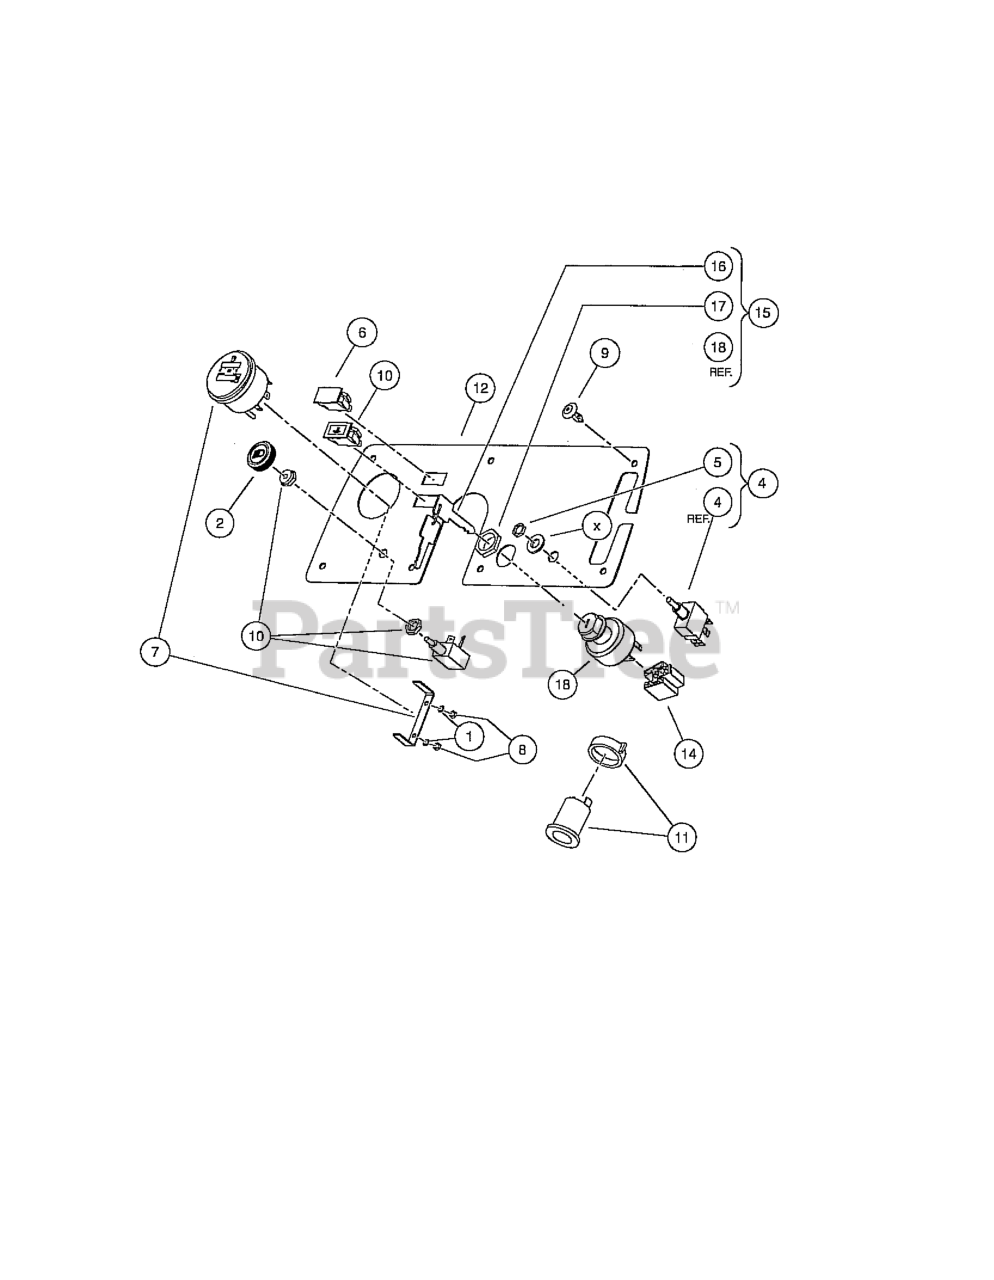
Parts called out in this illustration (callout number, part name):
1	Lockwasher, M4
2	LIGHT SWITCH KNOB
3	WASHER, 7/16 FLAT
4	TOGGLE SWITCH
6	LIGHT, OIL
7	GAUGE FUEL/HOUR
8	NUT, M4-.7
9	SCREW, TUFLOK PANEL, 1/4
10	SWITCH, LIGHT
11	ACCESSORY RECEPTACLE
12	PANEL, INSTRUMENT, DIESEL
13	2IGHT, INDICATOR, COLLANT TEMP
15	KEYSWITCH, DIESEL
16	KEY SET, AWD DIESEL
